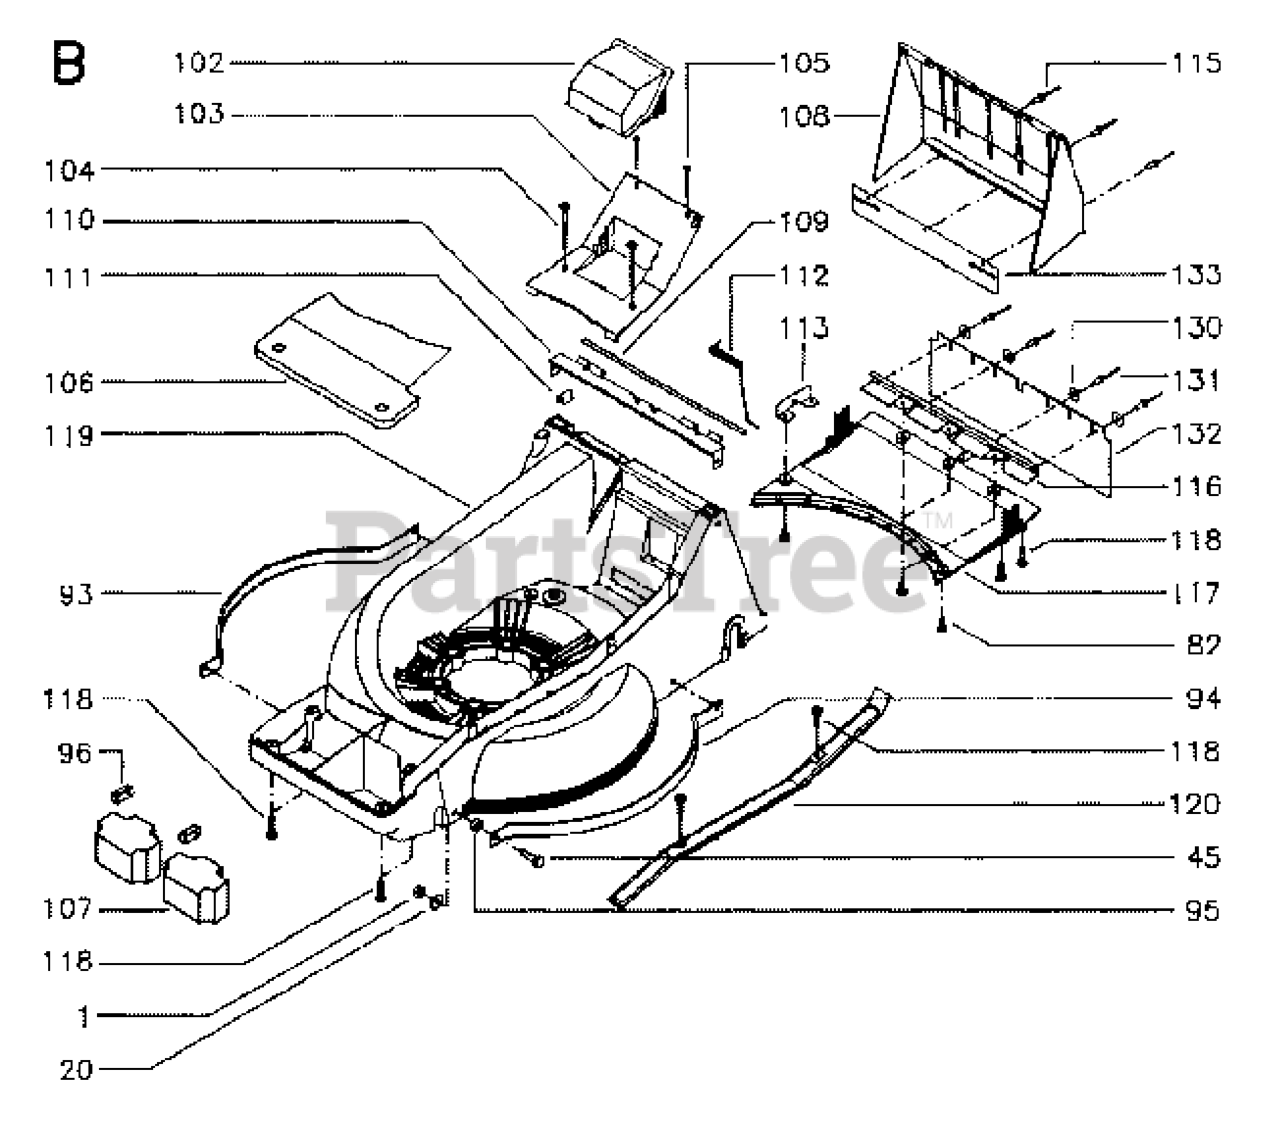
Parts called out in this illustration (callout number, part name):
2	KEY.SQUARE.187X2.500
7	HUB.ASM.WHEEL.REAR.22"
15	WASHER
17	SPRING.BRAKE.K46.GREEN
22	ROD.SHIFT.FENDER.STGT.
23	KNOB.DELUXE.(PISTOL.GRIP).BLAC
29	ROD.BRAKE.K46
35	ROD .BRAKE. PARKING. GT. HUSQ.
42	PEDAL COVER T
50	IDLER.FLAT.910.OFFSET
51	NUT LOCK FLG 3/8-16 UNC
52	IDLER.V-GROOVE.910.OFFSET
56	V-BELT.MOWER.92.40.42/K46
64	SHAFT.ASM.PEDAL.BRAKE.
70	SUBASM.CONSOLE.HUSQ.GT.HYDRO
73	BOLT.HEX.FLNG.5/16-18X3.75
74	SCREW.HI-LO.CONSOLE
80	STRAP.TORQUE.K46.K57R.TT
99	ROD.SPRING.BYPASS.K46.TEX.GT
116	NUT LOCK HEX FLANGE 5/16-18
125	SCREW
143	Screw 5/16-18 x 1/2 Hex, Self Tapping 5/16-18 x 1/2
153	RETAINER M
159	COTTER PIN
160	RETAINER CLIP
161	SPRING, RETURN LT
162	SPACER.TRANSAXLE.18&22
166	NUT.PUSH.625
167	LATCH.BRAKE.SPRING
170	KEEPER.CENTER SPAN.1.688
174	NUT.PUSH.500.2006
175	SHAFT ASM SHIFT
176	ARM.CLEVIS.ROD.SHIFT
178	SPRING.SHIFT.GT2006
183	SPACER.SPLIT.800X.350
184	RB HANDLE.PARKG.BRK.HUS/PRED
186	SPACER.RETAINER
187	WASHER 12/32X2X10GA
188	RP.LINK.CLUTCH.GROUND.DRIVE
189	BELLCRANK.GROUND.DRIVE.TEX.
190	KEEPER.BELLCRANK.DRIVE
196	SCREW 3/8-16X1
197	BRKT.ANIT-ROTATION.CLUTCH
211	BUSHING.SHAFT.BRAKE.HAND
216	BRACKET.PULLEY.IDLER.W/TEX
220	REFLECTOR.RH.TEX GT
221	RETAINER.SPRING.CLIP.H
225	KEEPER.BELT.TRANSAXLE.K46
226	BRKT.MOUNT.TORQUE.K46.
227	SCREW.THDROL.5/16-18X3/4.TTY
230	WASHER.HARDENED
231	IDLER.V-GROOVE.1.688.OFFSET
232	BOLT FIN HEX 7/16-14 X 1
233	WASHER SERRATED
279	LINK.SHIFT.T/A.K46.FEND.TX
